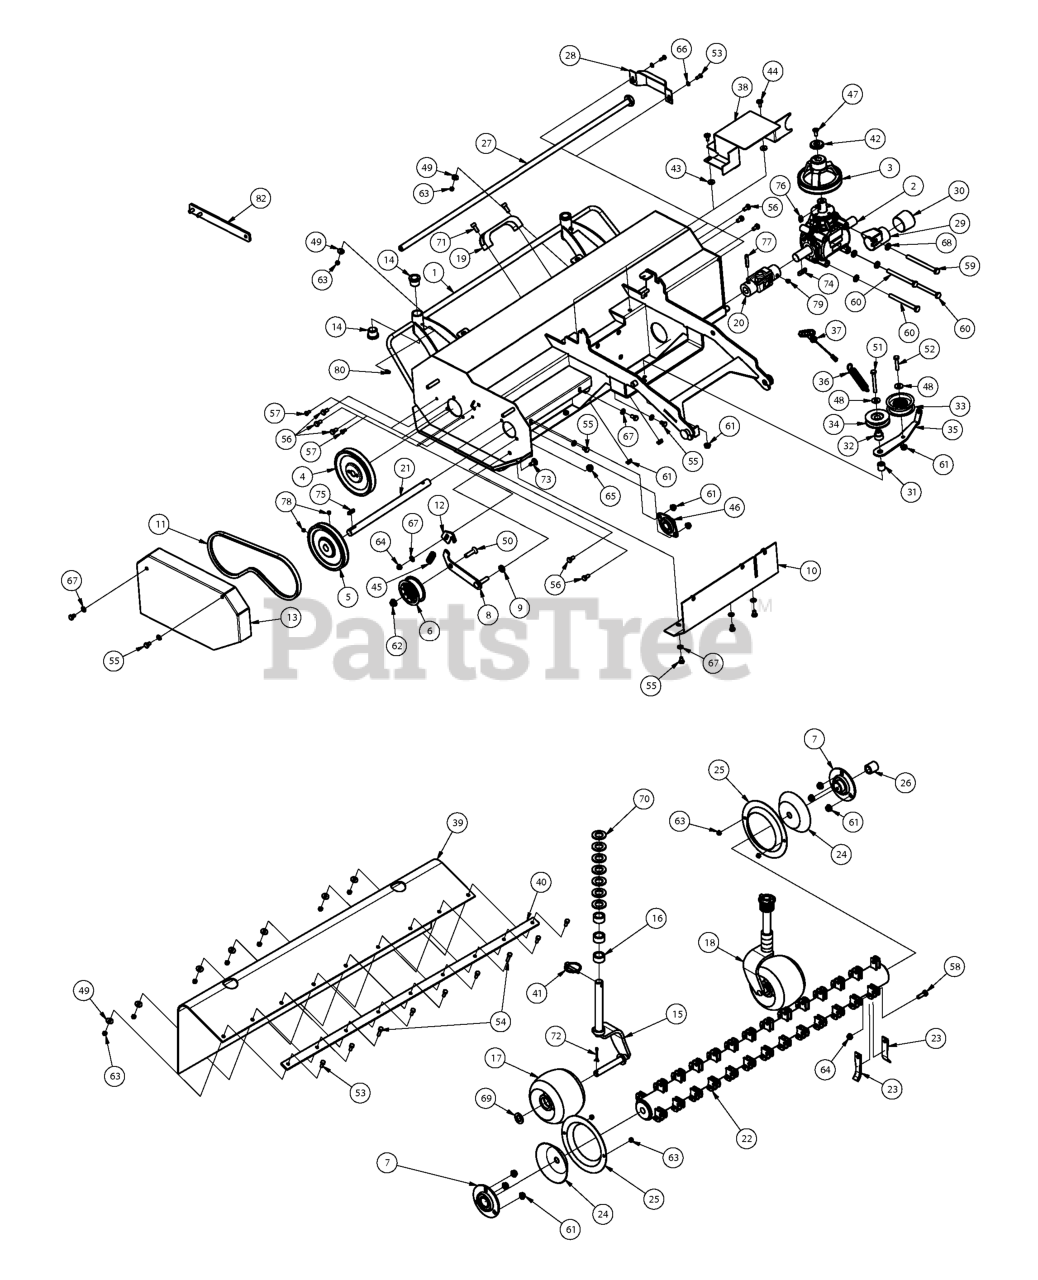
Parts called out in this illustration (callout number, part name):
4	PULLEY
11	BELT
14	BUSHING
17	DECK ROLLER, FRONT
20	LINK
21	DRIVE SHAFT
22	SHAFT
23	BLADE
25	PLATE
27	SCREW
28	HAND GUARD
29	GUARD
30	DUST COVER
33	IDLER PULLEY
34	PULLEY ASSY
40	REINFORCEMENT
44	SCREW
61	NUT LOCKING
63	NUT
64	NUT
65	NUT
71	SOCKET
73	SCREW
78	SCREW
79	SCREW
80	NIPPLE
82	KEY
